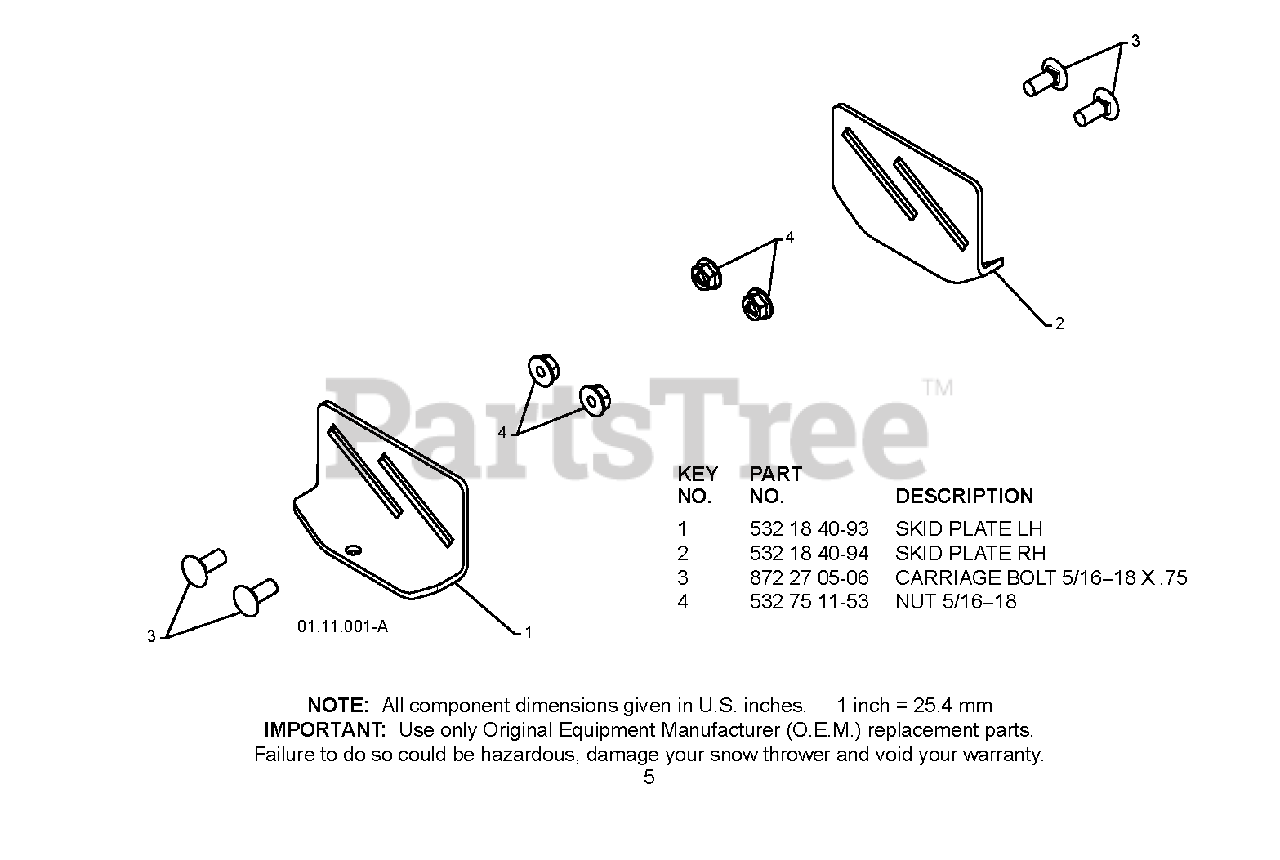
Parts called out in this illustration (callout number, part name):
1	SKID PLATE LH
2	SKID PLATE RH
4	NUT, LOCK 5/16-18
